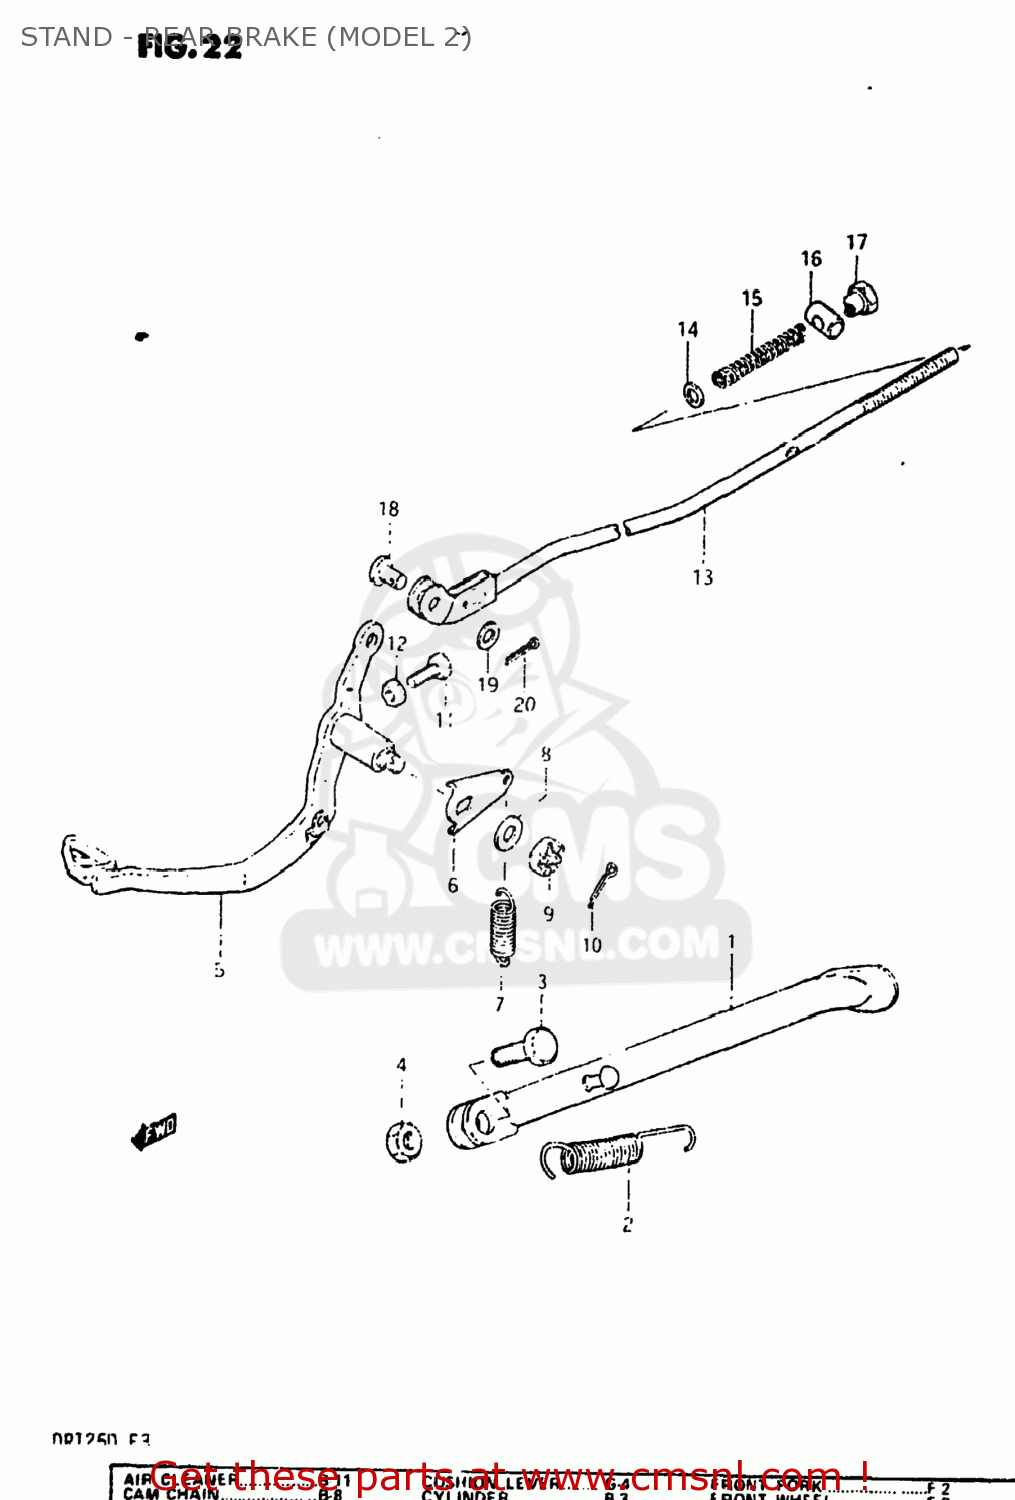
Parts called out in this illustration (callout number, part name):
1	STAND,SIDE
2	SPRING
3	BOLT(10X30)
4	NUT
5	PEDAL,BRAKE
6	ARM,BRAKE RETURN SPRING
7	SPRING
8	WASHER
9	NUT 8MM
10	PIN 20X20
11	BOLT(6X23)
12	NUT
13	ROD ASSEMBLY,REAR BRAKE
14	WASHER
15	SPRING
16	PIN
17	NUT
18	PIN
19	WASHER
20	PIN 20X20
